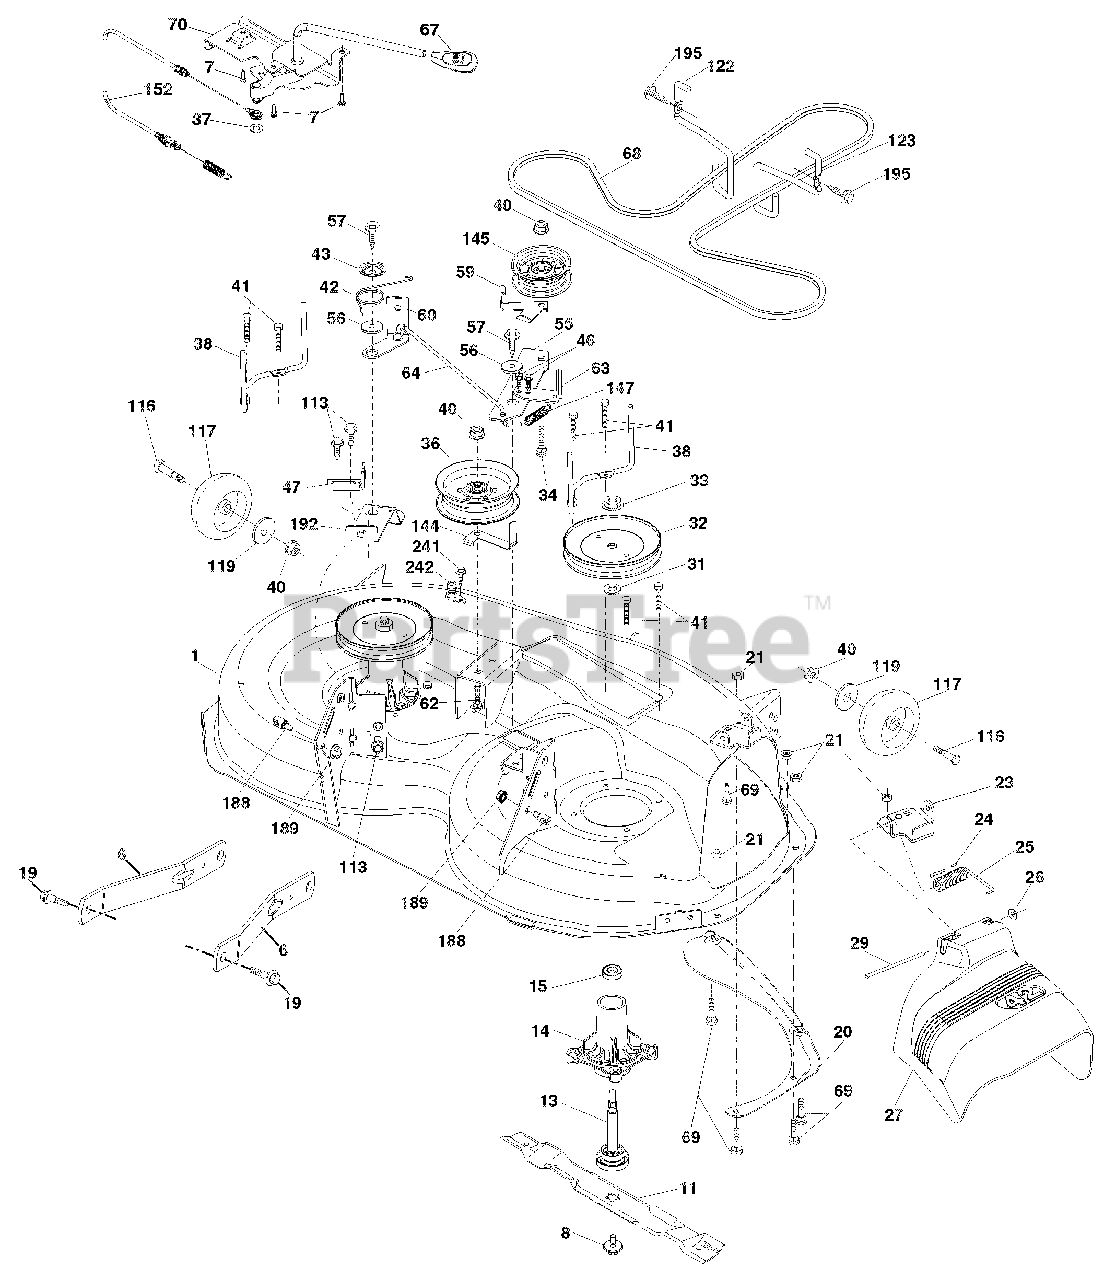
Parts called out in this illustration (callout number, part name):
1	HOUSING.MOWER.42"4-BLT.MANDREL
6	ARM.SUSPENSION.MOWER.REAR.LD
8	BOLT/WASHER ASM.7/16-20.UNF
11	BLADE.MOWER.42"HI LIFT PREMIUM
13	SHAFT ASM.MNDRL.N/GREASEABLE38
14	HOUSING.MANDREL.4PT.SERVICE
15	BEARING.BALL.MANDREL
19	BOLT.SHOULDER
20	BAFFLE.VORTEX.42.STD/HEAVY DTY
21	Nut, Hex, Crownlock 5/16-18
23	BRACKET.DEFLECTOR.38/42"2005
24	CAP.SLEEVE..80X.112.BLK.MOWER
25	SPRING.TORSION.DFL.38/42/46.GR
26	NUT.PUSH.PHOS.& OIL
27	SHIELD.DEFLECTOR.
29	ROD.HINGE.42/46"
31	WASHER.SPACER.MANDREL
32	PULLEY.MANDREL.5.438 PD.42"
33	NUT.FLANGE.LOCK.TOP
34	BOLT.CARR.SH.3/8-16X1-1/2.GR5
36	PULLEY.IDLER.4.50.RAW
37	WASHER.13/32 X 13/16 X 16 GA.
38	KEEPER.BELT.MANDREL.PULLEY
40	Nut, Hex, Flangelock 3/8-16
41	HEX HEAD BOLT
42	SPRING.TORSION.BRAKE
43	SPRING.TORSION.RETAINER
46	SCREW.THD.ROLL.1/4-20 X 5/8
47	BRACKET.CLUTCH.CABLE
55	IDLER.ARM
56	SPACER.RETAINER
57	SCREW.3/8-16X1.SMGML.TAP/R.BLK
59	GUARD.TUV.IDLER
60	ARM.BRAKE.MOWER.42"
62	BOLT.RD.HD.SQ.NK.3/8-16UNC X 2
63	ARM.BRAKE.MOWER
64	LINKAGE.BRAKE
67	HANDLE.CLUTCH.CABLE.LT TEX.428
68	BELT.DRIVE.100.97"
69	BOLT.RDHD.SQNK.5/16-18 X 5/8
70	CLUTCH ASM.
113	BOLT.5/16-18HEX.WHS.HD.LCKSERR
116	BOLD SHLD "A" 2.41 "B" 1.66
117	WHEEL.GAGE.HALF.SPOKED
119	Washer 3/8 x 7/8 x 14 Ga.
122	KEEPER.BELT.ENGINE.LH.LT.TEX
123	KEEPER.BELT.ENGINE.RH.LT.TEX
144	KEEPER.BELT.MOWER
145	PULLEY.IDLER 48"PRIMARY
147	SPRING.RETURN
152	CABLE.CLUTCH.MANUAL
188	STUD.FASTNER.W/'D'ANTI-ROTATIO
189	Nut, Lock Hex Flange 5/16-18 u
192	BRACKET.BRAKE.STAND.LH
195	SCREW.HEXWSH THDR3/8-16X3/4.BL
242	PORT WASHOUT
